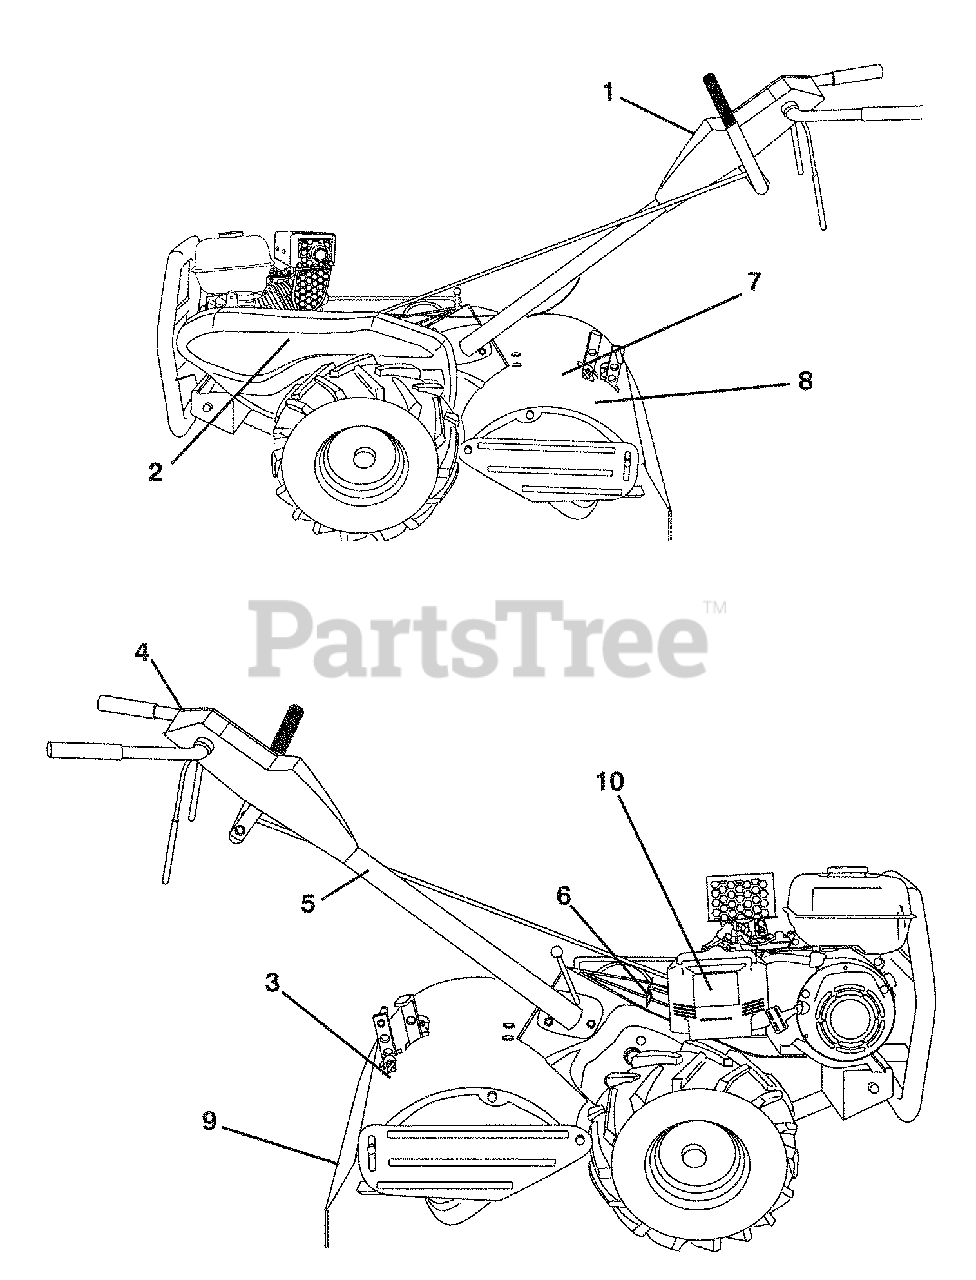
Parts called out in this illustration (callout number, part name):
1	Decal, Instruction, Tilling
2	Decal, Decal, Blt Grd
4	Decal, CNTRL PNL
5	Decal, Hand Placement
6	Decal, Shift Indicator
7	Decal, Shield
8	Decal, Forward
9	Decal, Warning, Rotating Tines
10	Decal, Air Cleaner
